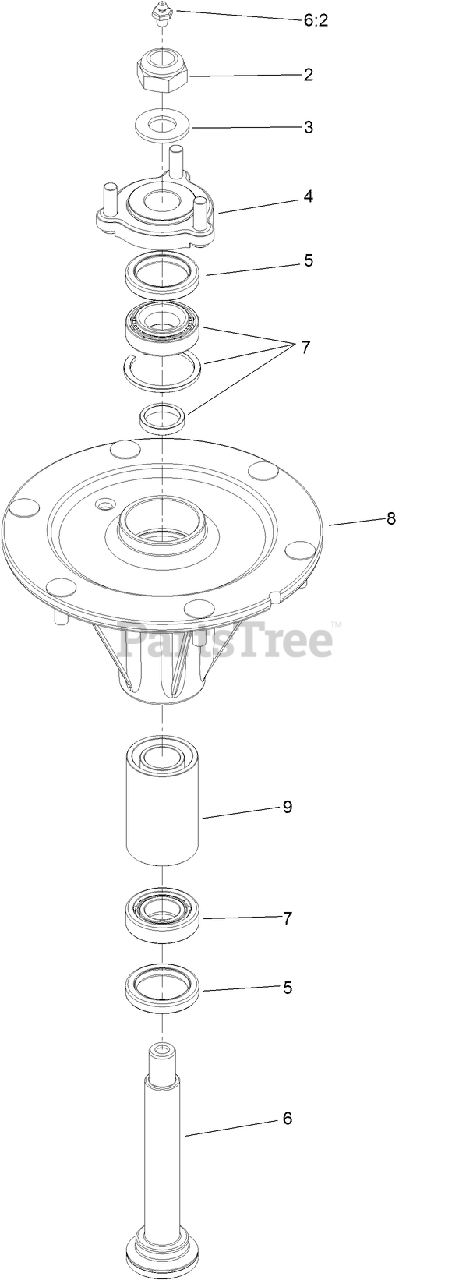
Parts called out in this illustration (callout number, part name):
2	NUT-LOCK, NI
3	WASHER
4	SPINDLE HUB ASM
5	SEAL-OIL
6	SHAFT-SPINDLE
6:2	FITTING-GREASE
7	TAPERED ROLLER BEARING SET
8	HOUSING-SPINDLE
9	SPACER SET
